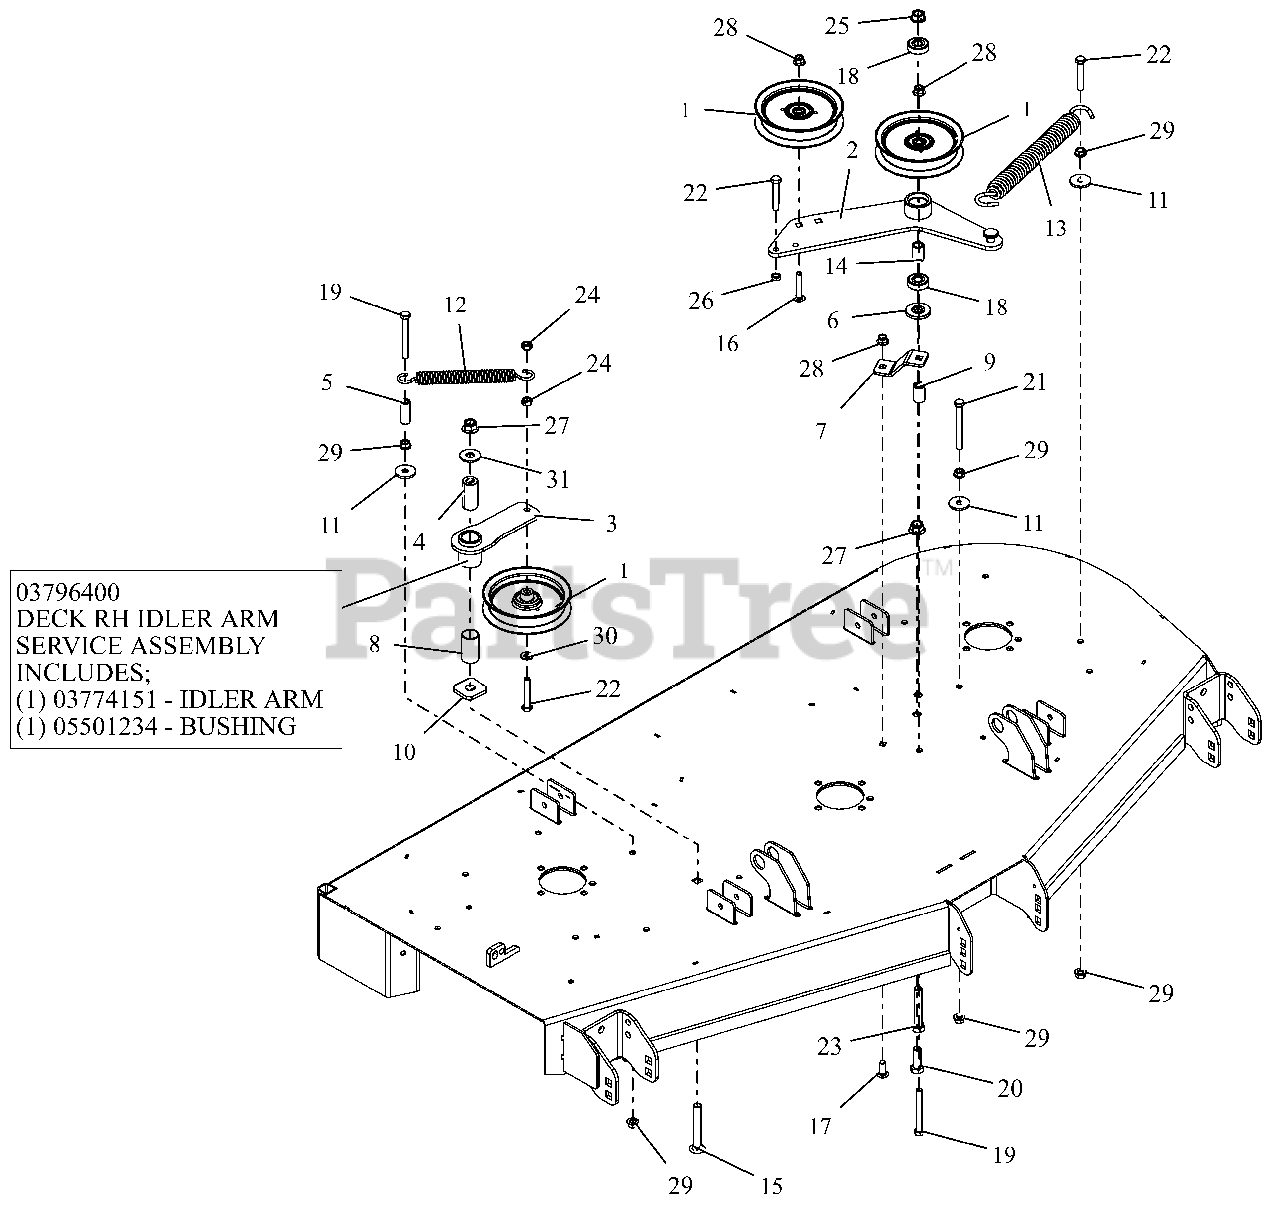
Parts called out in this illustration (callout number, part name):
1	IDLER, FLAT 5.00"
2	DECK PTO IDLER ARM WLDMT - BLK
3	WMT, IDLER ARM - BLACK
3	ASM, IDLER ARM (DECK)
3	BSHG, 1.00X1.125X1.937
4	BSHG, SPCR .502X.997X2.03 PM
5	SPACER, .375IDX.625ODX1.66 PM
6	SPACER, IDLER ARM
7	PTO FIXED IDLER MTG BRKT -RED
8	BSHG, 1.00X1.125X1.937
9	BUSHING, SLV .380X.750X1.190
10	WSHR-FLT .640X1.75X.250
11	WSHR-FL-STL .406X1.375X.135 YZ
12	SPRING, EXTENSION
13	SPRING, EXTENSION
14	SPACER .510 X .75 X 1.1485
15	@BLT-RDHDSQNK .50-13X3.50 G5YZ
16	BLT-RDHDSQNK .38-16X2.00 SHTYW
17	@BLT-RDHDSHSQNK.38-16X1.0 G5YZ
18	BRG-BALL .500X1.38X.437
19	@BLT-HEX .38-16X3.25 GR5 YWZC
20	@BLT-HEX .50-13X1.50 GR5 YWZC
21	@BLT-HEX .38-16X3.50 GR5 YWZC
22	@BLT-HEX .38-16X2.25 GR5 YWZC
23	@BLT-HEX .50-13X3.00 GR5 YWZC
24	@NUT-LK-CTR .38-16 YWZC
25	NUT-LK-CTR-FLG .50-13 YWZC
26	NUT-HEX-JAM .375-16 YWZC
27	@NUT-LK-NYL-FLG .50-13 YWZC
28	@NUT-LK-NYL-FLG .38-16 YWZC
29	@NUT-SPNLK-FLG .375-16 YWZC
30	@WSHR-FL-STL.406X.812X.065 YWZ
31	@WSHR-FL-STL.563X1.38X.109YWZC
